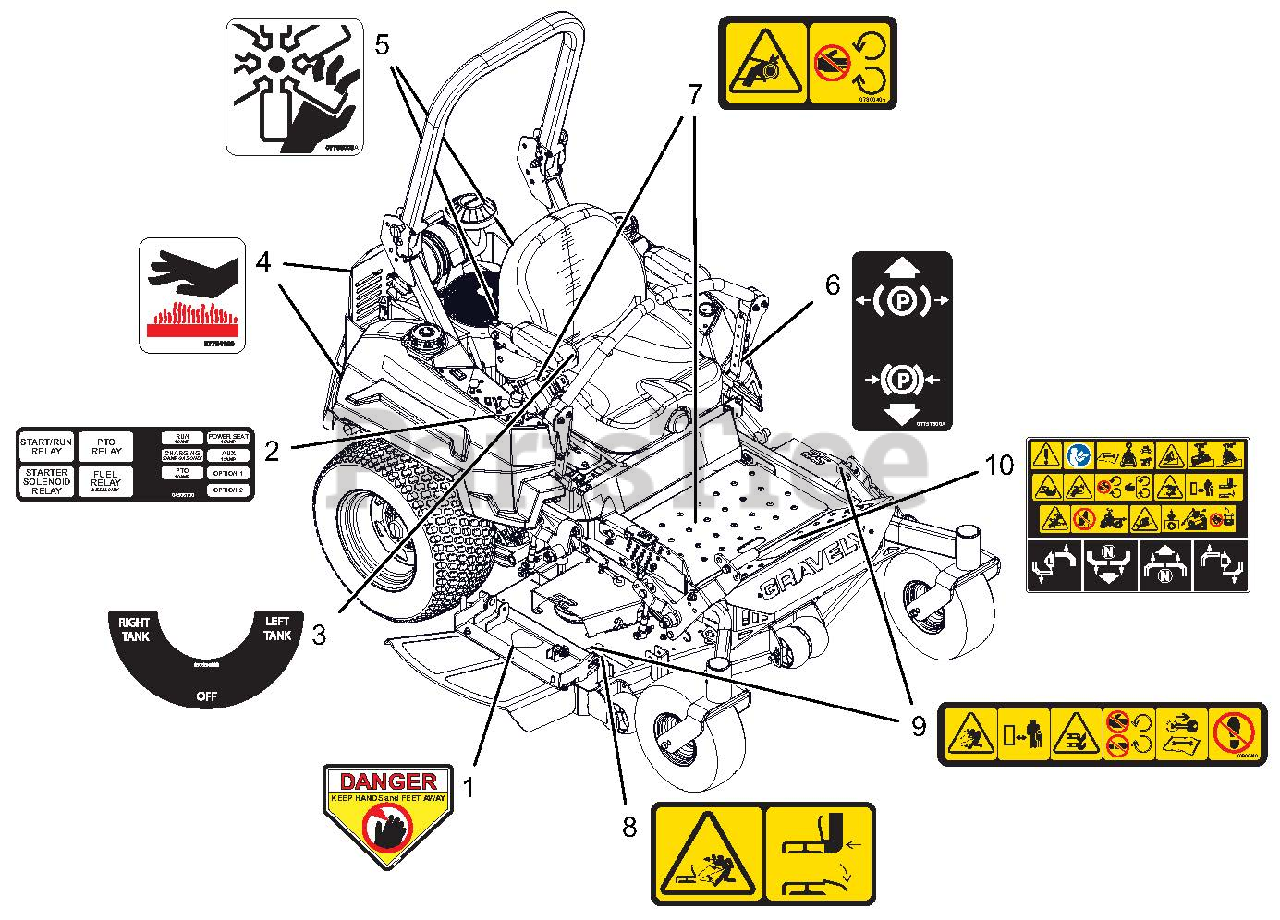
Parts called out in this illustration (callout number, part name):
1	DECAL, DANGER
2	DECAL, FUSE BOX
3	DECAL- FUEL CONTROL VALVE
4	DECAL, HOT SURFACE
5	DECAL, DANGER FAN
6	DECAL, PARKING BRAKE LEVER
7	DECAL, SAFETY - GUARDING
8	DECAL, SAFETY - DECK GUARDING
9	DECAL, DECK SAFETY
10	DECAL, INSTR SAFETY
